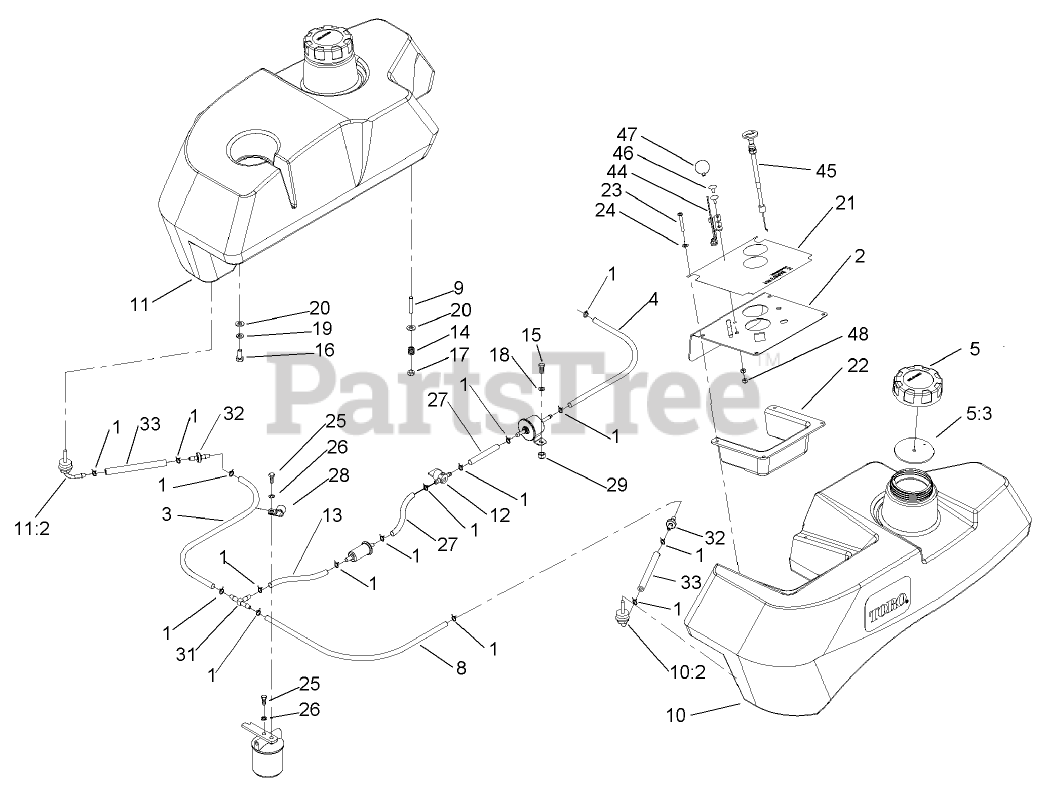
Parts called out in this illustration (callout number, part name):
2	Panel-Control
3	HOSE-FUEL
4	Hose-Fuel
5	GAS CAP ASM
5:3	GASKET-CAP, GAS
8	HOSE-FUEL
10	LH Fuel Tank ASM
10:2	FITTING-FUEL, BULKHEAD
11	RH Fuel Tank ASM
11:2	FITTING-FUEL, BULKHEAD
12	VALVE-FUEL
13	HOSE-FUEL
14	SPRING-TANK, FUEL
15	SCREW-HH
16	SCREW-HH
17	NUT-LOCK, NI
18	WASHER-FLAT
19	WASHER-LOCK
20	WASHER-PLAIN
21	Decal-Panel, Control
22	SHIELD-PANEL, CONTROL
24	WASHER-SPRING
25	SCREW-HH
26	WASHER-LOCK
27	HOSE-FUEL
28	CLIP-LOOM
29	NUT-HF
31	FITTING-TEE, BARBED
32	VALVE-CHECK, FUEL
33	HOSE-FUEL
44	THROTTLE CABLE ASM
45	Control-Choke, Push / Pull
46	BOLT-CARR
47	KNOB-BALL
48	NUT-LOCK, NI
49	TIE-PLASTIC
